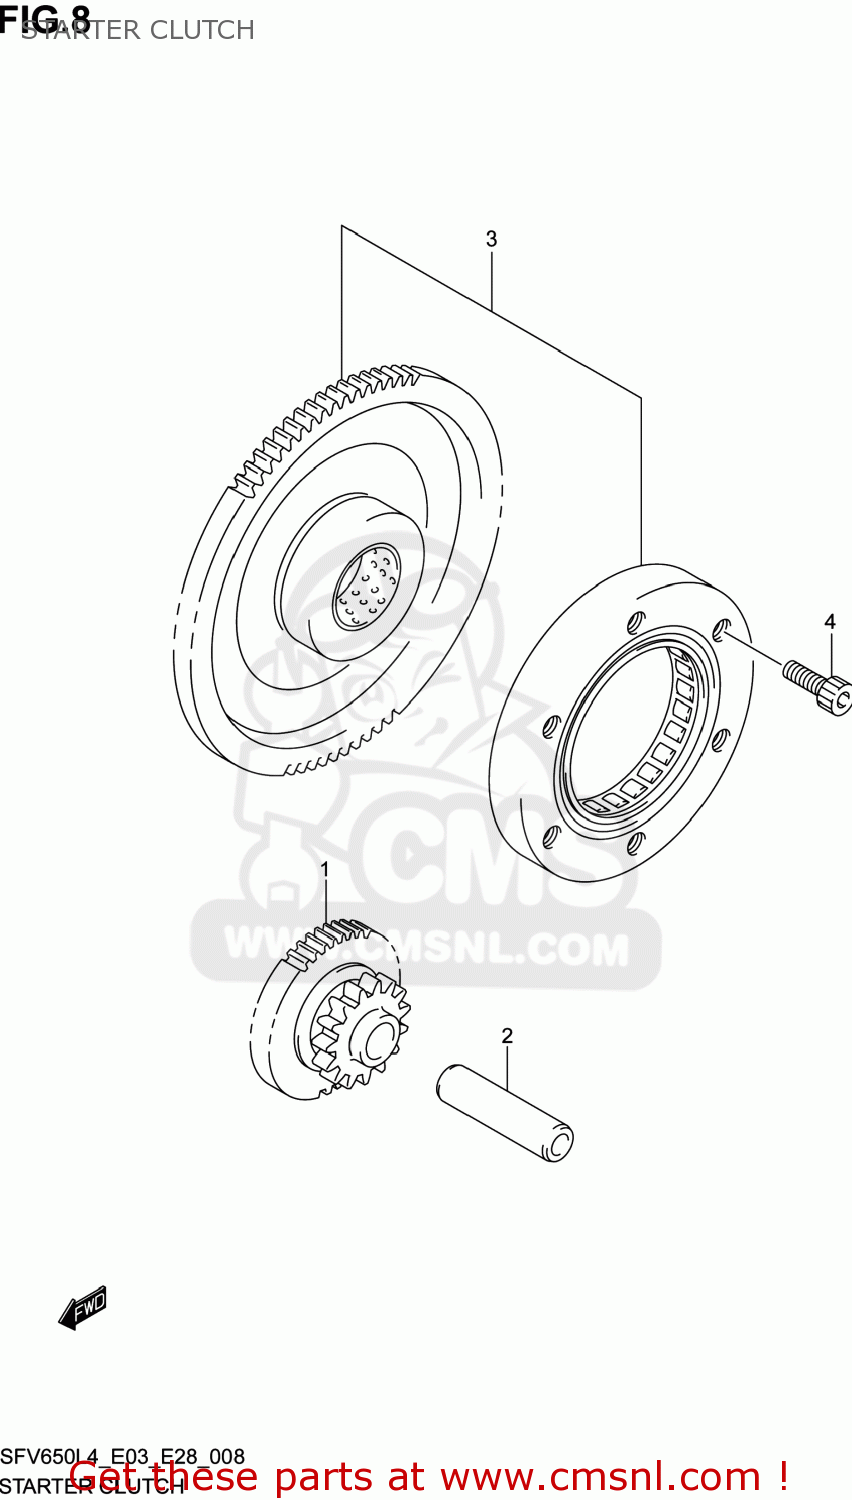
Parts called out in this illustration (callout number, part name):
1	GEAR,STARTER IDLE
2	PIN(8X12X45.5)
3	CLUTCH SET,STARTER
4	BOLT(8X16)
